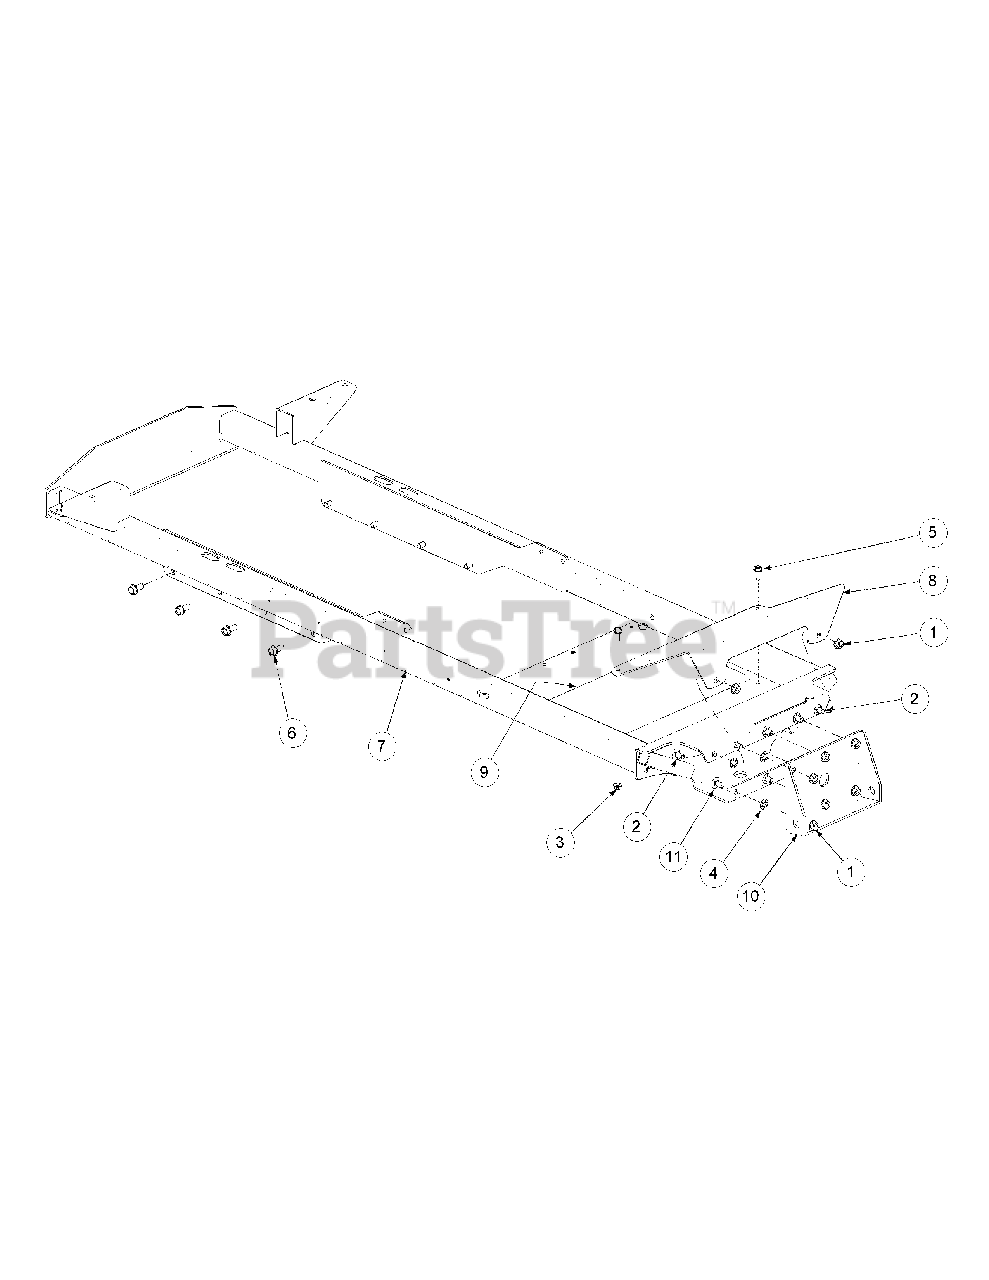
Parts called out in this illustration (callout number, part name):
1	Flange Lock Hex Nut, 3/8-16
2	Carriage Bolt, 3/8-16 x .75 Lg
3	Hex Flange Lock Nut, 5/16-18
4	Push Retainer, 3/8
5	Self Tapping Screw 5/16-18 x .750
6	Self Tapping Screw 3/8-16 x .875
7	Frame Assembly
8	Foot Rest Bracket
9	Abrasive Pad
10	Front Axle Bracket Assembly
11	Carriage Bolt, 3/8-16 x 1.00
